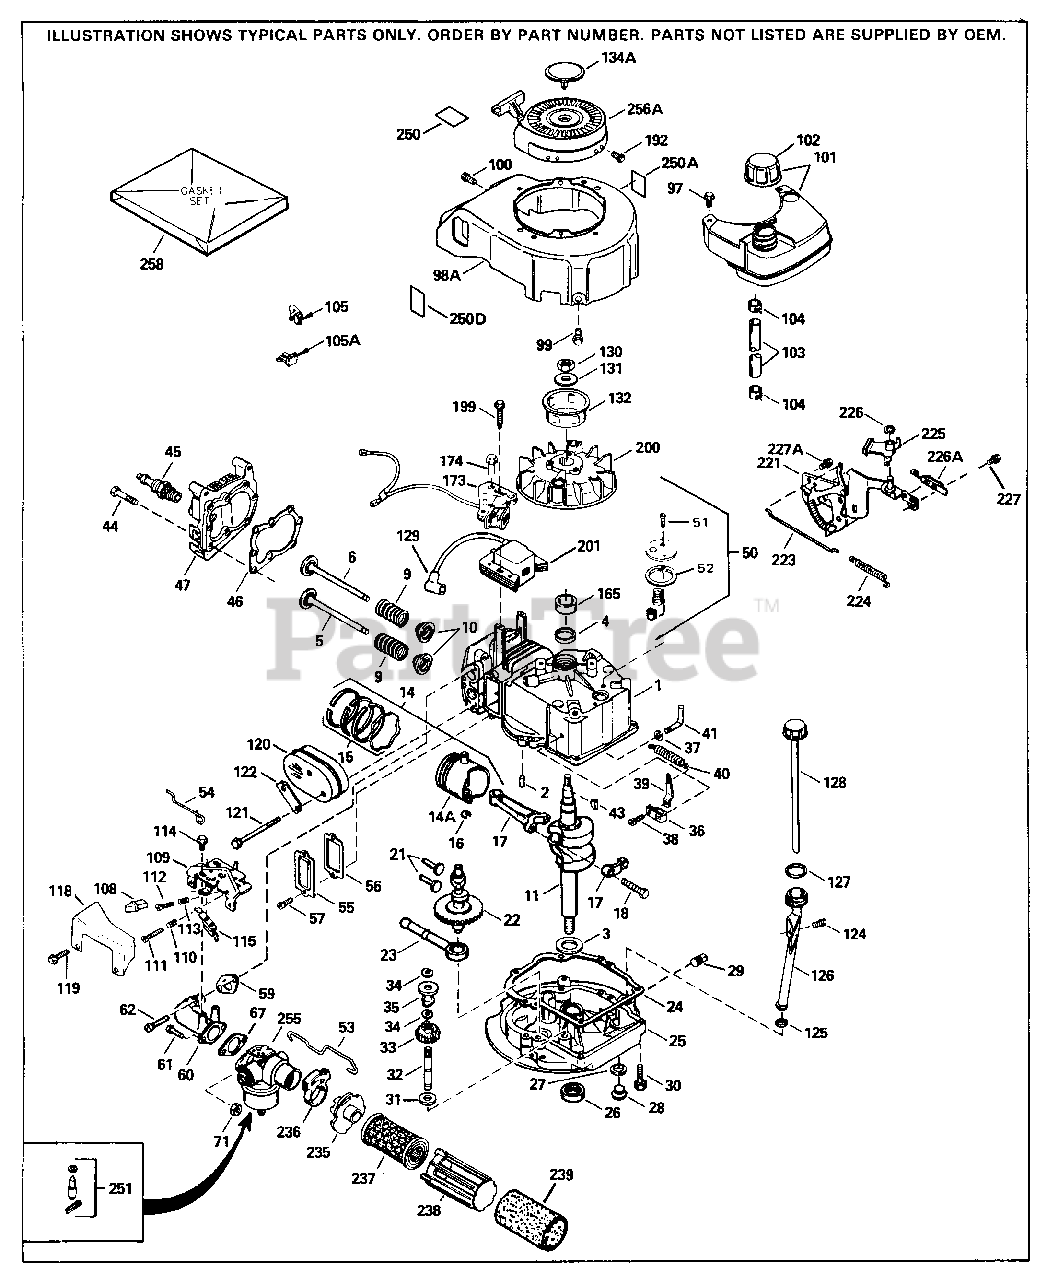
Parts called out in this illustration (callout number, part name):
1	"Cylinder (Incl. 2 & 4) (2-5/8" Bore)
2	Dowel Pin
3	Washer, Thrust
4	Seal, Oil
5	Exhaust Valve (Std.) (Incl. 151) (Con ventional Ports)
5	Exhaust Valve (1/32" OS) (Incl. 151) (Conventional Ports)
6	Intake Valve (Std.) (Incl. 151) (Conv entional Ports)
6	Exhaust Valve (1/32" OS) (Incl. 151) (Conventional Ports)
9	Spring, Valve
10	Cap, Lower valve spring
11	Crankshaft
14	Piston, Pin & Ring Set (Std.) 2-5/8" Bore
14	Piston, Pin & Ring Set (.010" OS)
14	Piston, Pin & Ring Set (.020" OS)
14A	Piston & Pin Ass'y. (Incl. 16)(Std.) 2-5/8"
14A	Piston & Pin Ass'y. (Incl. 16) .010" OS
14A	Piston & Pin Ass'y. (Incl. 16) .020" OS
15	Ring Set (Std.) (2-5/8" Bore)
15	Ring Set (.010" OS)
15	Ring Set (.020" OS)
16	Piston Pin Retaining Ring
17	Rod Assy., Connecting (Incl. 18)
18	Bolt, Connecting rod
21	Valve Lifter
22	Camshaft (MCR)
23	Oil Pump Ass'y.
24	* Gasket, Mounting flange
25	Flange Ass'y. (Incl. 26, 28, 29 & 32)
26	Oil Seal
27	* Drain Plug Gasket Not req. w/plastic plug
28	Plug, Oil drain
30	Screw, 1/4-20 x 1-1/4"
31	Washer, Flat
32	Shaft, Mechanical governor
33	Gear Assy., Governor (Incl. 31)
34	Retaining Ring
35	Spool, Governor
36	Clamp, Governor lever
37	Flat Washer
38	Screw, 8-32 x 5/16"
39	Lever, Governor
40	Spring, Governor
41	Rod, Governor (Incl. 37)
43	Flywheel Key (also available in Packa ged Part #740007B)
44	Screw, 5/16-18 x 1-1/2"
45	Resistor Spark Plug (RJ19LM) also ava ilable in Packaged Part #740081
46	* Gasket, Cylinder head
47	Head, Cylinder
51	Screw, 10-24 x 9/16"
53	Link, Governor-to-throttle
54	Link, Governor spring
55	Cover, Valve spring box
56	* Gasket, Valve spring cover
57	Screw, 10-24 x 1/2"
59	* Gasket, Intake
60	Pipe, Intake (Incl. 59)
61	Screw, 1/4-28 x 7/8"
62	Screw, 1/4-20 x 1"
67	* Gasket, Carburetor
71	Nut & Lock Washer 1/4-28
98A	Housing, Blower
99	Screw, 1/4-20 x 1/2"
100	Screw, 10-24 x 9/16"
102	Fuel Cap (Red)
103	Fuel Line (Braided 16")
104	Fuel Line Clamp
108	Control Knob
109	Control Bracket Incl. 110,111,112,11 3 & 115
110	Spring, Compression
111	Screw, 6-32 x 17/32"
112	Screw, 6-50 x 7/16"
113	Spring, Compression
114	Screw, 10-24 x 9/16"
121	Screw 1/4-20 x 2-3/4"
122	Plate, Lock
124	Screw, 10-32 x 1/2"
125	Gasket, Oil fill tube
126	Oil Fill Tube
127	"O" Ring
128	Dipstick
129	Cover, Spark plug
130	Nut, Flywheel
131	Washer, Belleville
132	Hub, Starter
165	Spacer, Flywheel Key
192	Screw, 8-32 x 1/2"
199	Screw, 10-24 x 1"
200	Flywheel
201	Solid State Assy.
221	Bracket Assy., S.E. Brake
223	Link, Control
224	Spring, Extension
225	Lever, Brake
226	Ring, Retaining
226A	Terminal Assy.
227	Screw, 1/4-20 x 3/8"
239	Filter, Pre-air (Use as required) Po ly
251	Inlet Needle, Seat & Clip Assy.
255	Carburetor (Incl. 67) (Refer to Divis ion 5, Section A, page 196 for breakd own)
256A	Rewind Starter Refer to Division 5, S ection C, page 34 for breakdown
258	* Gasket Set (Incl. items marked *)
